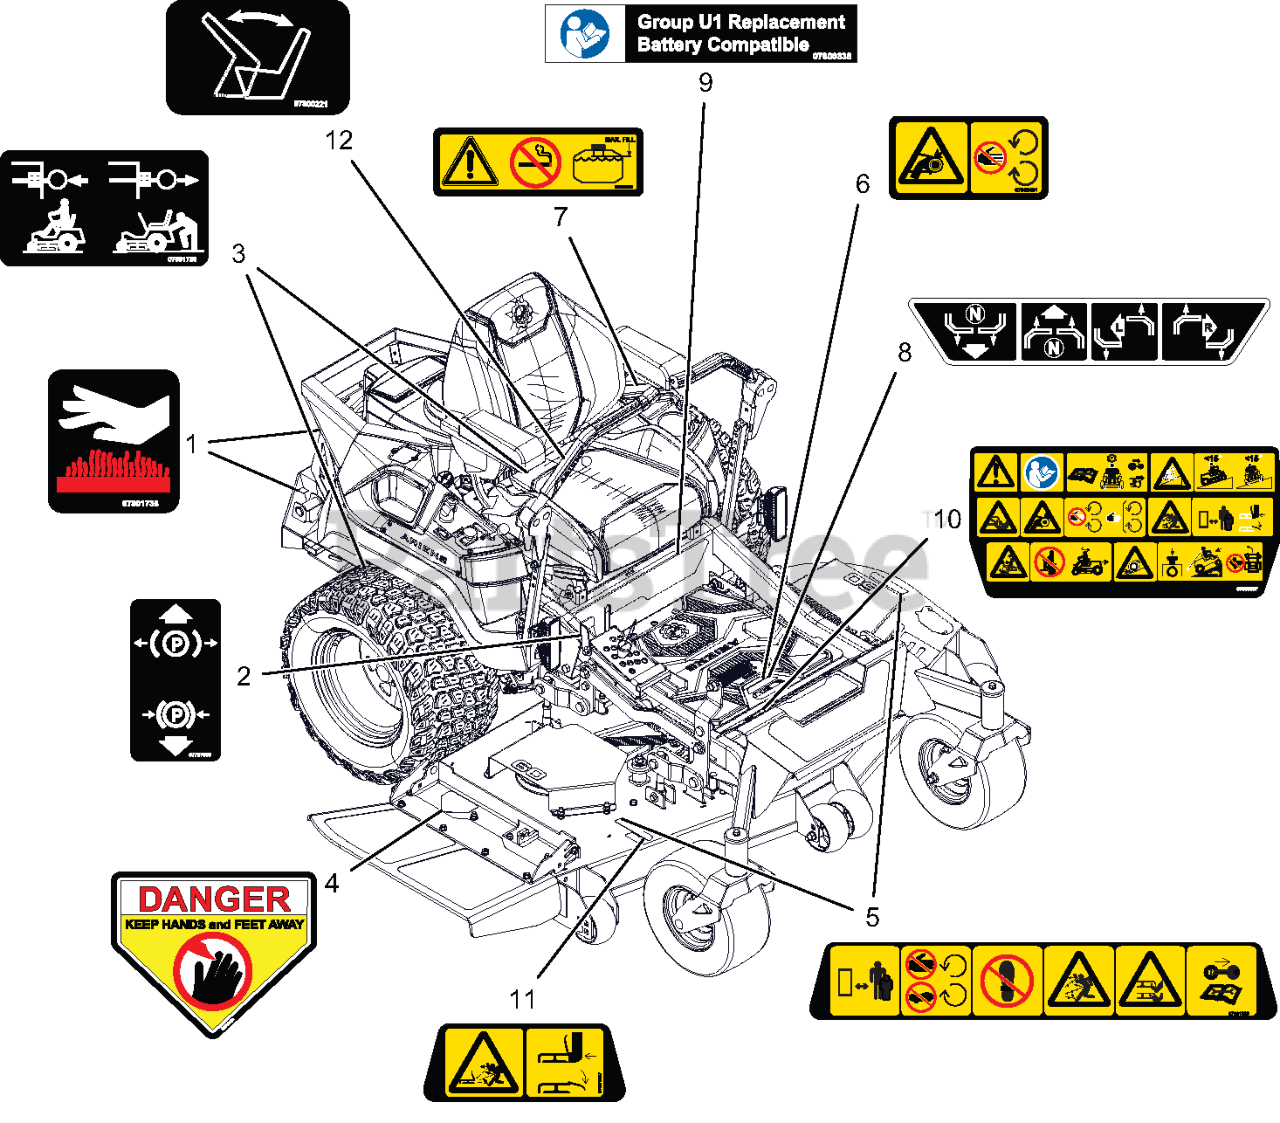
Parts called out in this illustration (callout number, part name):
1	DECAL- HOT SURFACE
2	DECAL, PARKING BRAKE LEVER
3	DECAL- TRANSAXLE DISCONNECT
4	DECAL, DANGER
5	DECAL- SAFETY - MOWER DECK
6	DECAL, SAFETY - GUARDING
7	DECAL, FUEL WARNING
8	DECAL, INSTRUCTION - STEERING
9	DECAL, U1 BATTERY REPLACEMENT
10	DECAL, MAIN SAFETY
11	DECAL- SAFETY - DECK GUARDING
12	DECAL - SEAT RELEASE
